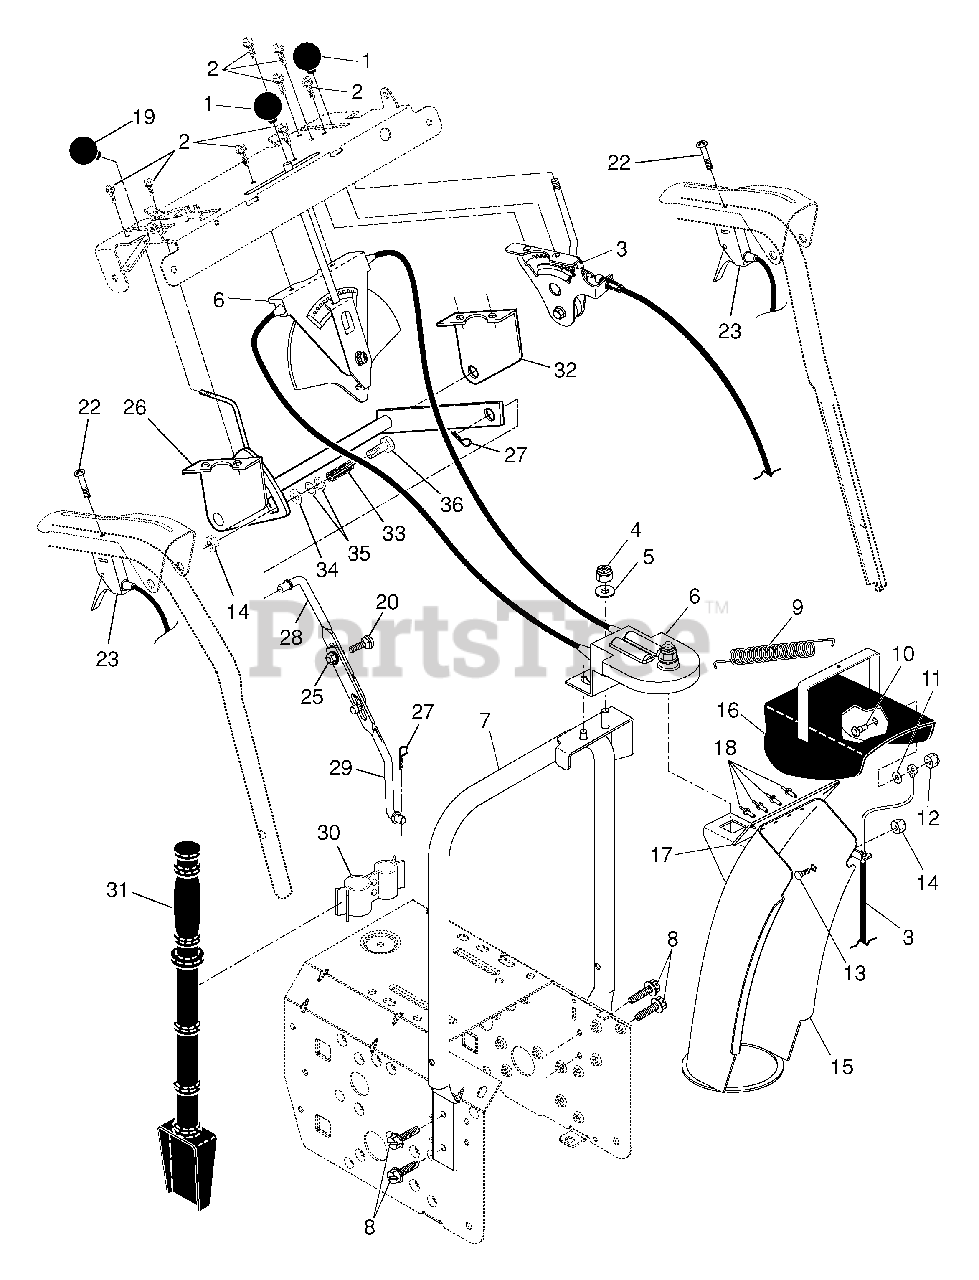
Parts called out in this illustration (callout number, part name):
1	Knob, Lever
2	Screw #10-24 x 5/8
3	Control Assembly, Deflector
4	Nut, Lock 3/8-16
5	Washer, Flat 3/8
6	Control Assembly, Chute Rotater
7	Support, Pivot
8	Screw, Hex Head 5/16-18 x 3/4
9	Spring, Deflector
10	Bolt, Shoulder
11	Washer, Friction, Nylon
12	Nut, Lock 1/4-20
13	Bolt, Carriage 5/16-18
14	Nut, Hex
15	Chute Assembly
16	Deflector Assembly
17	Seal, Deflector
18	Rivet, Blind
19	Knob, Speed Control Lever
20	Bolt, Carriage 5/16-18 x 3/4
22	Screw #10-24 x 1-1/2
23	Control Assembly, Power Steering
25	Nut, Hex, Flangelock 5/16-18
26	Lever Assembly, Speed Control
27	Retainer, Hairpin
28	Rod, Upper, Speed Control
29	Rod, Lower, Speed Control
30	Clamp, Mounting, Clean-Out Tool
31	Tool, Clean-Out
32	Bracket, Shift
35	Washer, Friction
